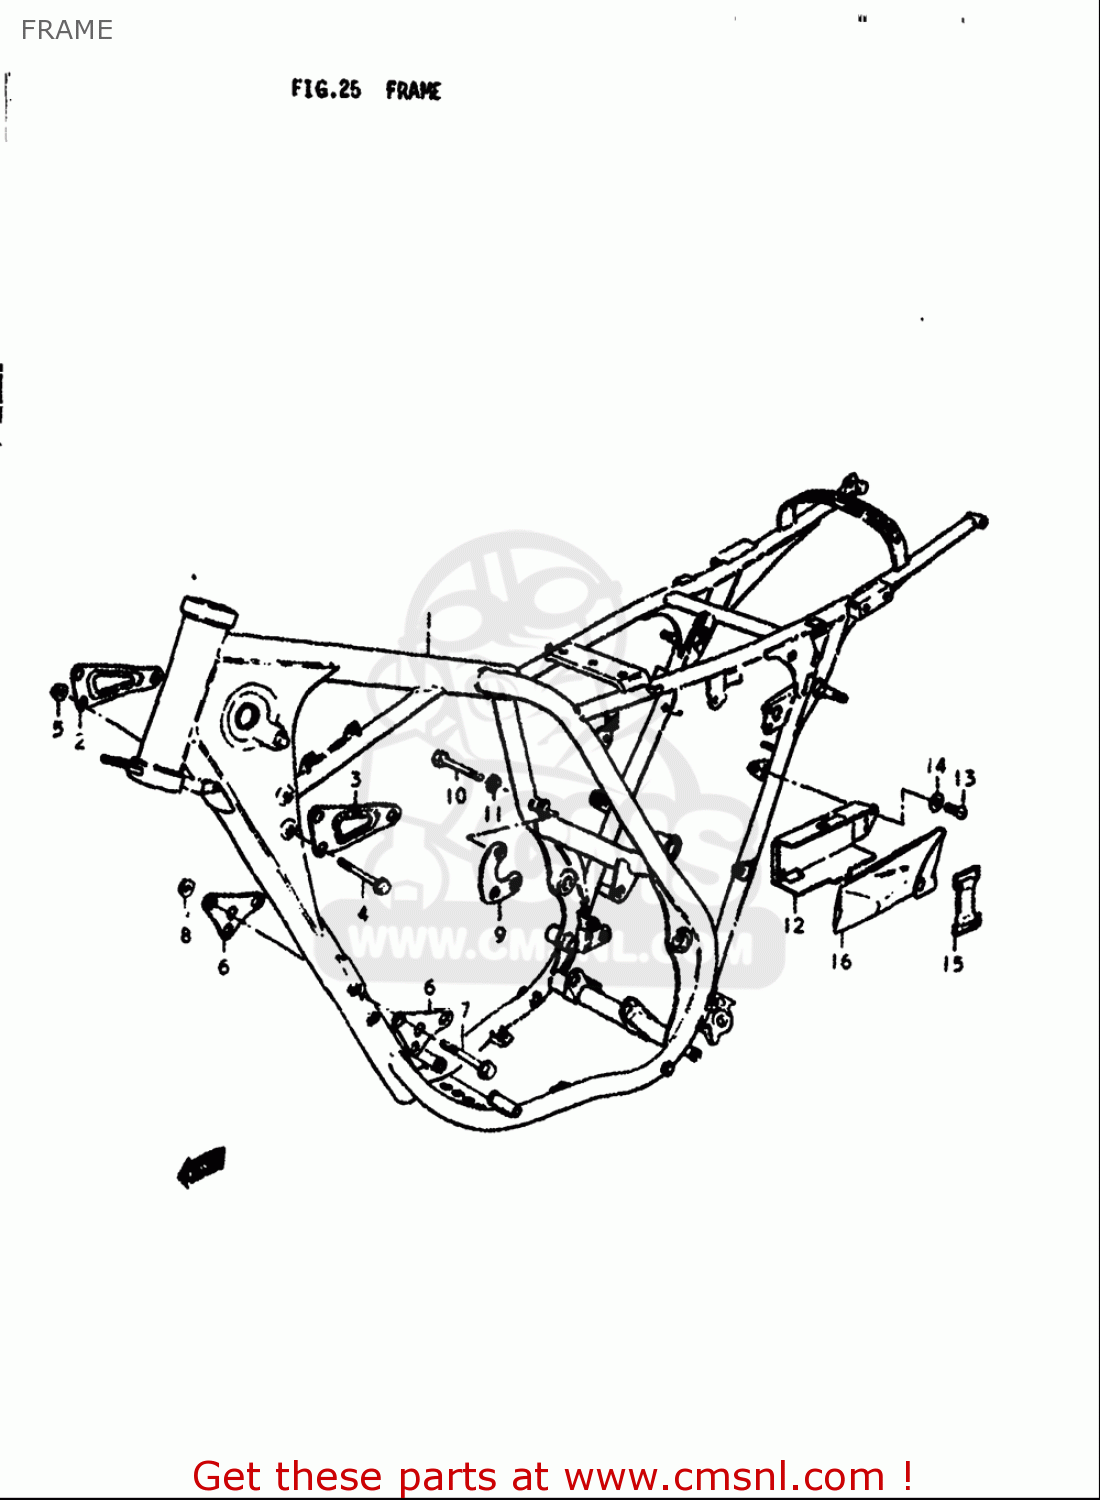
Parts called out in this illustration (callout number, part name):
4	BOLT
5	NUT
6	PLATE,ENGINE MOUNTING
7	BOLT
8	NUT
10	BOLT
11	WASHER,LOCK
13	SCREW
14	WASHER
15	BAND
16	TOOL ASSY
